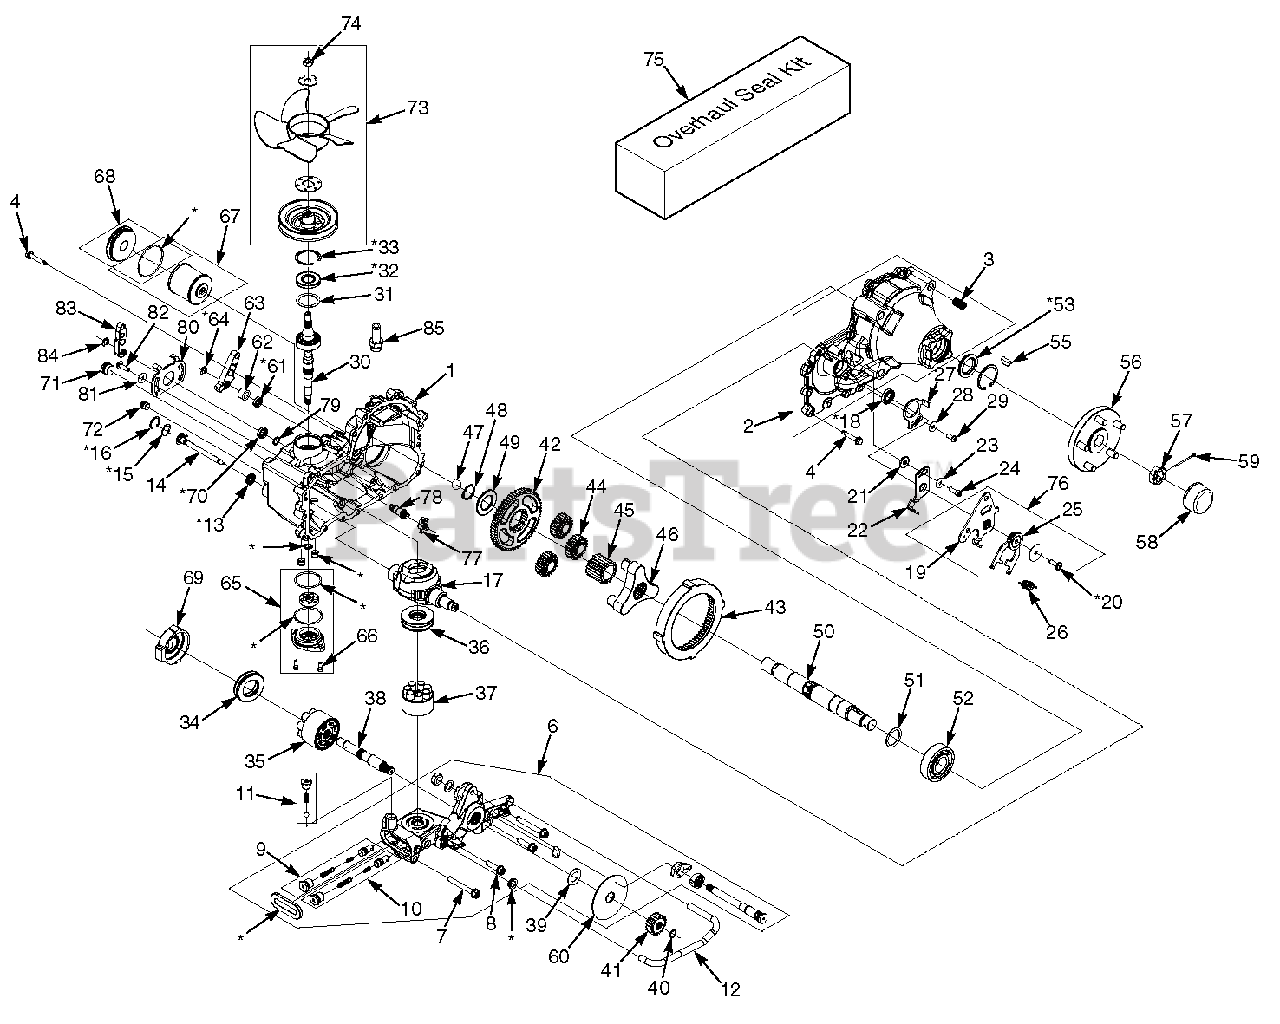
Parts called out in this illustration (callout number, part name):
1	Kit, Housing Main, LH
2	Kit, Housing Side, LH
3	Insert, 1/2-13 x 1-1/2" UNC
4	Screw, Hex Flange 5/16-18 x 1-1/2"
5	Tube, Sealant
6	Kit, Center Section, LH
7	Bolt, Hex Flange 3/8-16 x 3"
8	Screw, Hex Flange Head 3/8-16 x 1-1/2"
9	Kit, Shock Valve
10	Kit, Shock Valve
11	Kit, Charge Relief
12	Tube, Filter, LH
13	Seal, Lip 12x 24 x 5 TC
14	Kit, Bypass Actuator
15	Spring, Wave
16	Ring, Retaining, HO-100
17	Swash Plate, 16cc. Machined
18	Seal, Lip 22 x 32 x 7
19	Arm, Control, LH
20	TWHCS, 5/16-18 x 1"
21	Spacer, .320 x 1.005 x .179
22	Arm, Neutral, LH
23	Washer, .34 x .88 x .06
24	SHCS, 5/16-24 x .875
25	Assembly, RTN Uni-Directional (CCW) LH
26	Spring, Extension, RTN - 44lbs
27	Plate, Stop, LH
28	Washer, .34 x .88 x .06
29	HBHCS, 5/16-18 x 3/4"
30	Kit, Input Shaft
31	Spacer
32	Seal, Lip 25 x 52 x 7 TC
33	Ring, Retaining Internal
34	Bearing, Thrust 42 x 68 x 16
35	Kit, Cylinder Block - 21cc.
36	Bearing, Thrust 35 x 70 x 22
37	Kit, Cylinder Block - 16cc.
38	Shaft, Motor
39	Washer, .89 x 1.50 x .04
40	Ring, Retaining
41	Gear, 19T
42	Gear, 65T
43	Gear, Ring 68T
44	Gear, Planet 23T
45	Gear, Sun 22T
46	Carrier
47	Ball, Thrust .75
48	Ring, Retaining 1-1/4"
49	Spacer, Thrust, Axle
50	Shaft, Axle
51	Washer, 1.40 x 1.75 x .05
52	Bearing, Ball 35 x 80 x 21
53	Seal, Lip 1.375 x 2.062 x .250
54	Ring, Retaining Internal
55	Key, Shaft, Axle
56	Kit, Hub, 5-Bolt
57	Nut, Hex 1-20 Slotted
58	Cap, Axle
59	Pin, Cotter 9/64 x 2"
60	Rotor, Brake
61	Seal, .56 x .88 x .19
62	Spacer, .57 x .86 x .53
63	Handle, Actuating
64	Ring, Retaining
65	Kit, Charge Cover
66	Screw, 1/4-20 x .625
67	Kit, Filter
68	Kit, Filter Plug
69	Plate, Motor Swash
70	Seal, 15 x 24 x 7
71	Plug, 7/8-14
72	Plug, 9/16-18
73	Kit, Fan/Pulley
74	Nut, Hex 1/2-20 w/Patch
75	Seal Kit
76	Kit, RTN Bi-Directional LH
77	Cam, 2-Speed
78	Shaft, 2-Speed, Bevel
79	Ring, Retaining External .59"
80	Arm, Lock Down 2-Speed
81	Washer, .34 x .88 x .06
82	HBHCS, 5/16-18 x 3/4"
83	Handle, Actuating
84	Ring, Retaining External .375"
85	Fitting, 7/8-14 SAE, .625 Beaded
